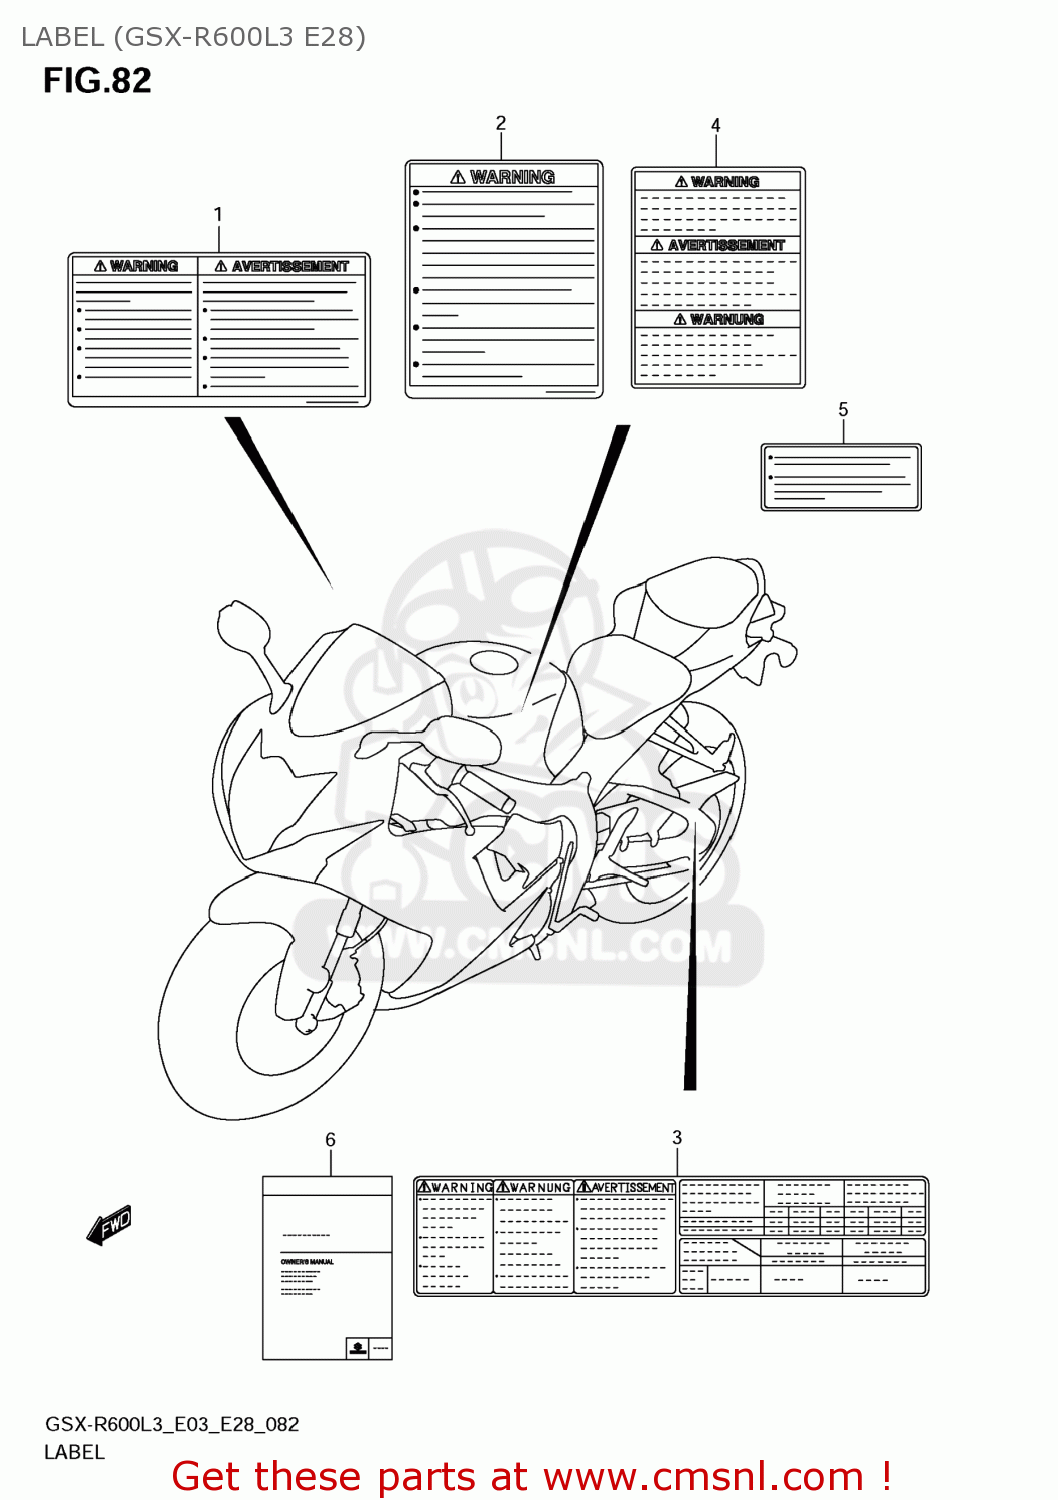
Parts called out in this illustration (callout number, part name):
1	LABEL,GENERAL WARNING
2	LABEL,SCREEN
3	LABEL,TIRE INFORMATION
4	LABEL,WARNING STEERING
5	LABEL,FUEL INFORMATION
6	MANUAL,OWNER'S
